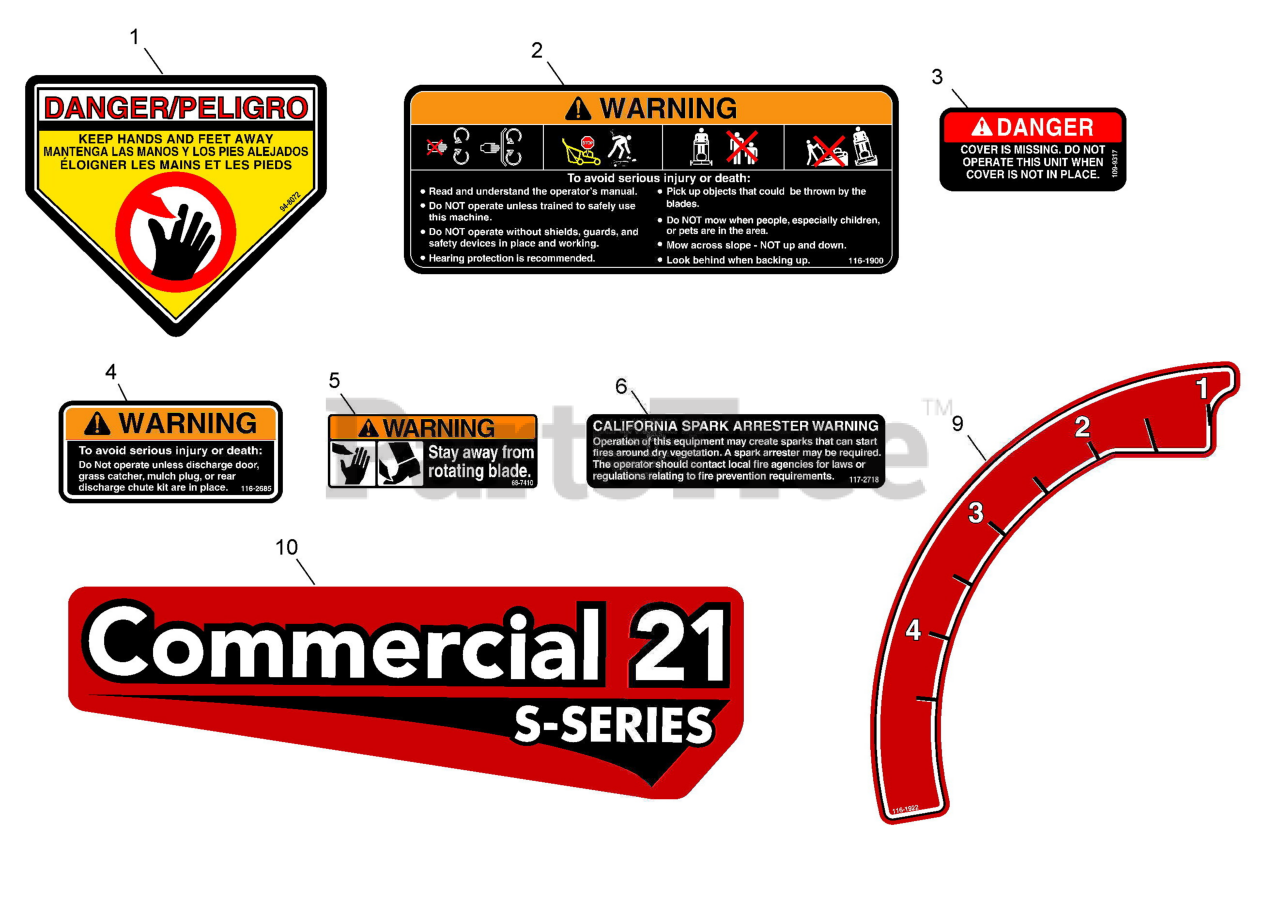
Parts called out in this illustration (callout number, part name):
1	DECAL-DANGER
2	DECAL-WARNING
3	DECAL-COVER MISSING
4	DECAL-WARNING DOOR SM
5	DECAL-BLADE
6	DECAL-ARRESTER, SPARK
9	DECAL-HEIGHT OF CUT
10	DECAL-COMM 21 S-SERIES
